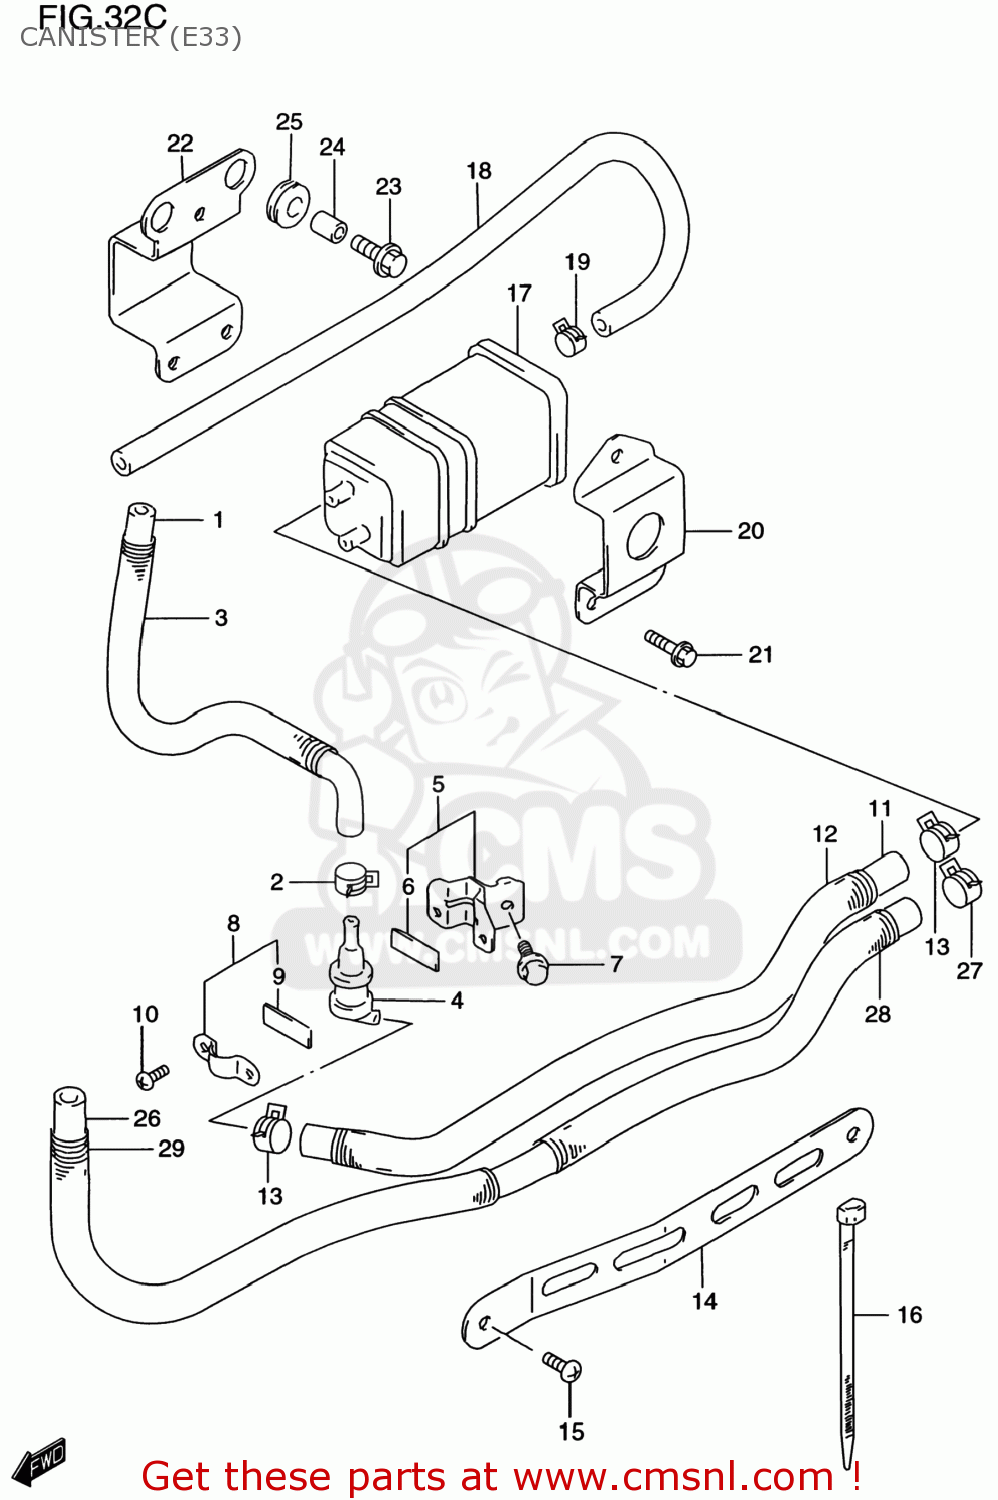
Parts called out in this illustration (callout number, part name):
1	HOSE,TANK & VALVE (CHARCOAL)
2	CLIP
3	SPRING
4	VALVE,FUEL TANK BREATHER
5	PLATE,BREATHER VALVE
6	CUSHION
7	BOLT
8	PLATE,FUEL TANK BREATHER NO.2
9	CUSHION
10	SCREW
11	HOSE(5.4X11.4X600)
12	SPRING
13	CLIP
14	PLATE,CANISTER HOSE
15	SCREW 6X12
16	CLAMP(L:125)
17	(CA) CANISTER ASSEMBLY
18	HOSE(7X12X600)
19	CLIP
20	PLATE,CSTR UPR
21	BOLT
22	PLATE,CSTR LWR
23	BOLT(6X20)
24	SPACER(6.5X10X9.4)
25	CUSHION
26	HOSE(5.4X11.4X2000)
27	CLIP
28	SPRING
29	SPRING
